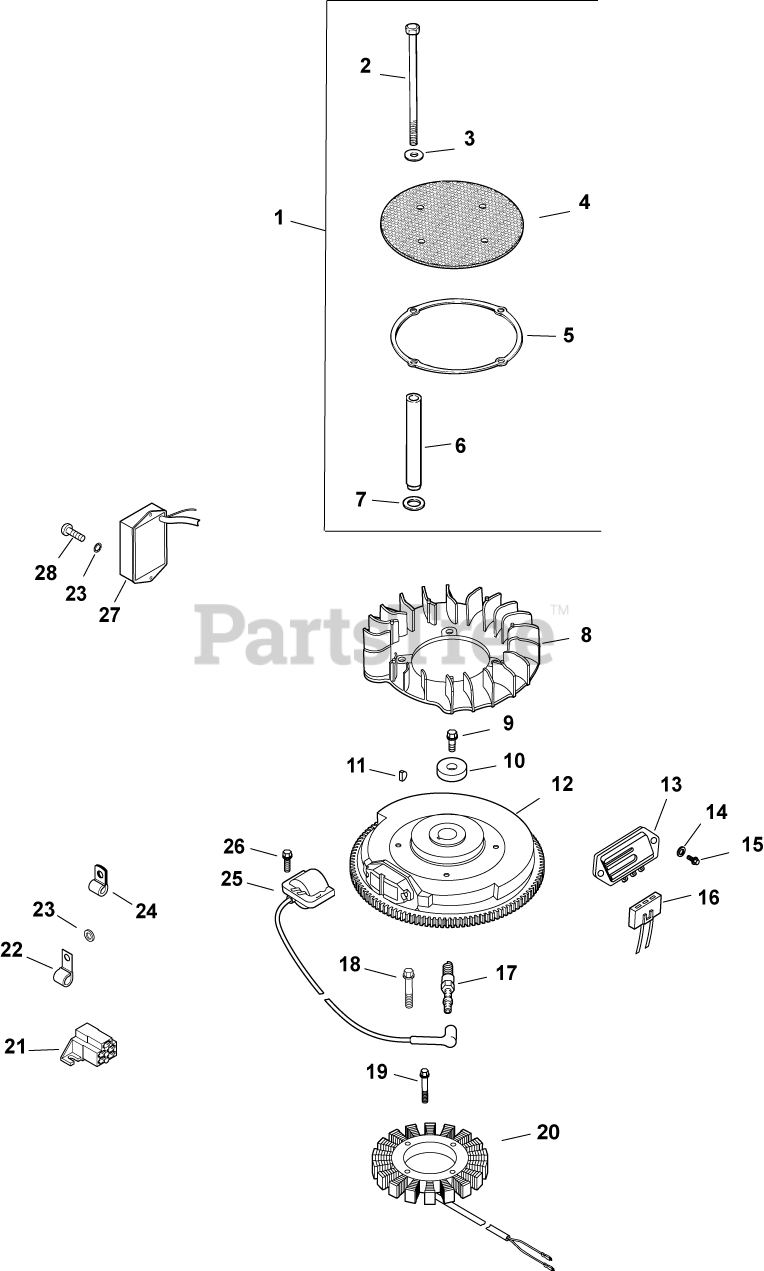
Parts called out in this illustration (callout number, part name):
1	KIT, CHOPPER SCREEN
2	SCREW, CAP M6X1.0X99.5
3	WASHER, FLAT 1/4" (O.D. 5/8")
4	SCREEN, GRASS-USE 24 162 41-S
5	RING, SUPPORT USE 25 141 08-S
7	WASHER, SPRING 10 MM
9	SCREW, FLG M10X1.5X45 - (#25086361S)
10	WASHER, FLAT 13/32"
11	KEY, 3/16" X 5/8"
12	FLYWHEEL ASSEMBLY-USE 24 025 58-S
13	REG/RECTIFIER (20/25 AMP)-USE 25 403 20-
14	WASHER, FLAT 3/16"
15	SCREW, PHL HD #11-16X7/8"
16	CONNECTOR, BODY (KM)-USE 25 155 41-S
17	PLUG, SPARK (PRO SERIES)
18	SCREW, M5X0.8X25 - (#25086402S)
19	SCREW, SKT SET #10-24X1/4"
20	KIT, 15 / 20 AMP STATOR
21	CONNECTOR
22	CLIP, TUBE & WIRING (KM)
23	WASHER, FLAT 1/4" (O.D. 1/2")
24	CLIP, CABLE
25	MODULE, IGNITION
26	SCREW, FLG THD FRM M5X.8X20-(#25086399S)
27	MODULE, SPEED ADVANCE -USE 24 755 172-S
28	SCREW, THD FRM M4X0.7X10
2458452-S	MODULE, SPARK ADV -USE 24 584 89-S
